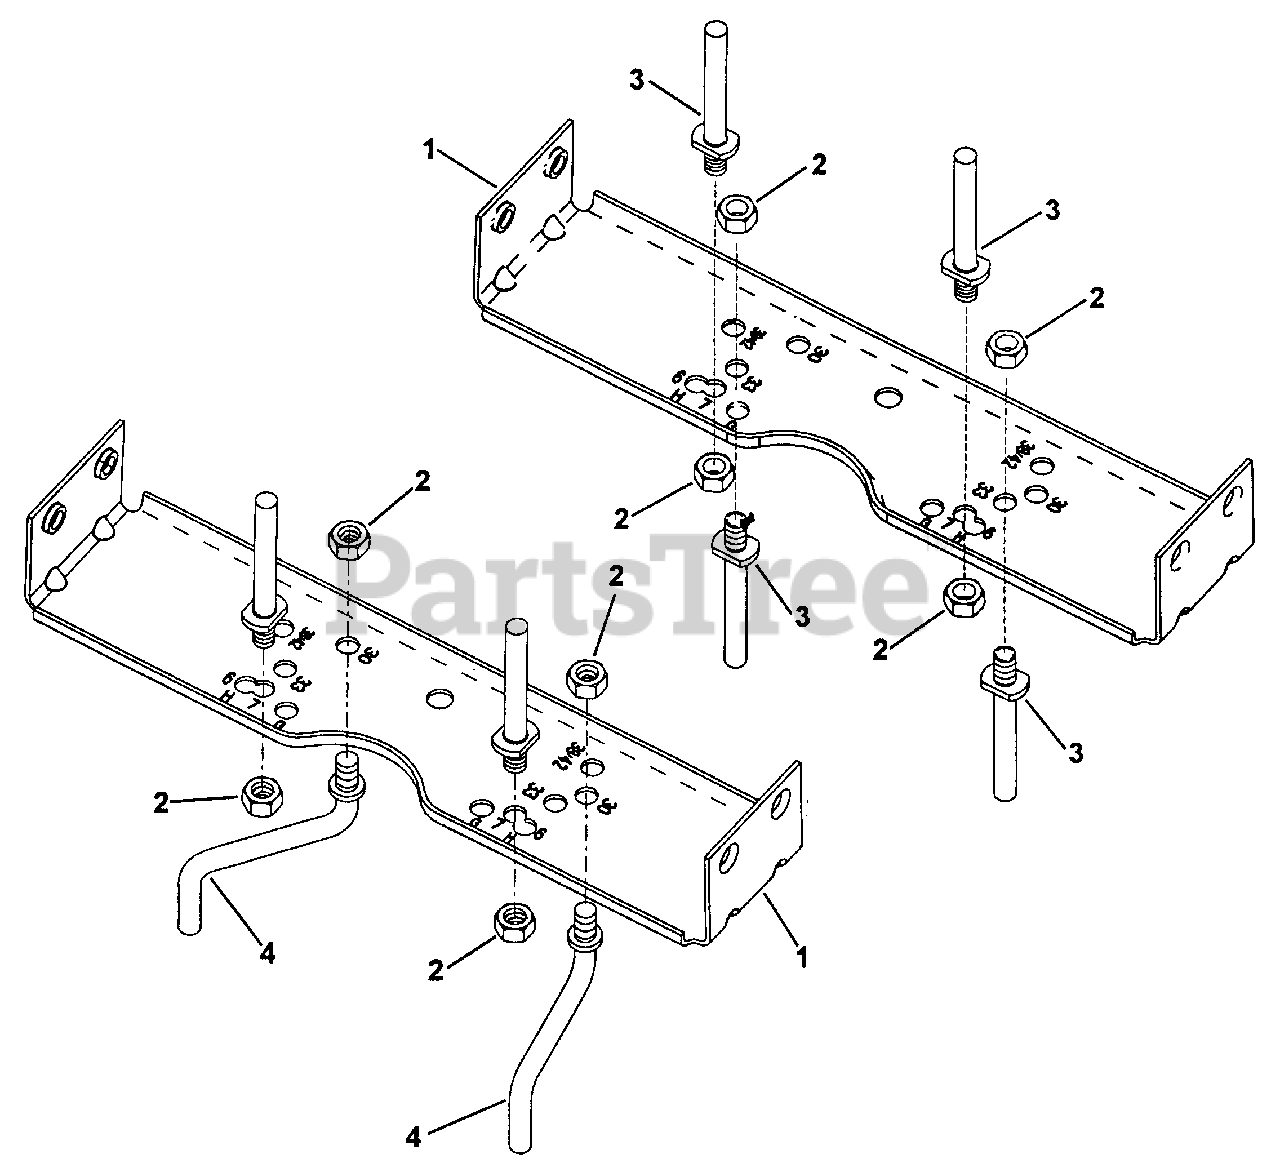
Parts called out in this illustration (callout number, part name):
1	BRACKET, Belt Guide
2	NUT, 5/16-18 Hex Center Lock, Grade B or 5
3	STUD, Belt Guide
4	STUD, Belt Guide 38" Dual Brake Deck
